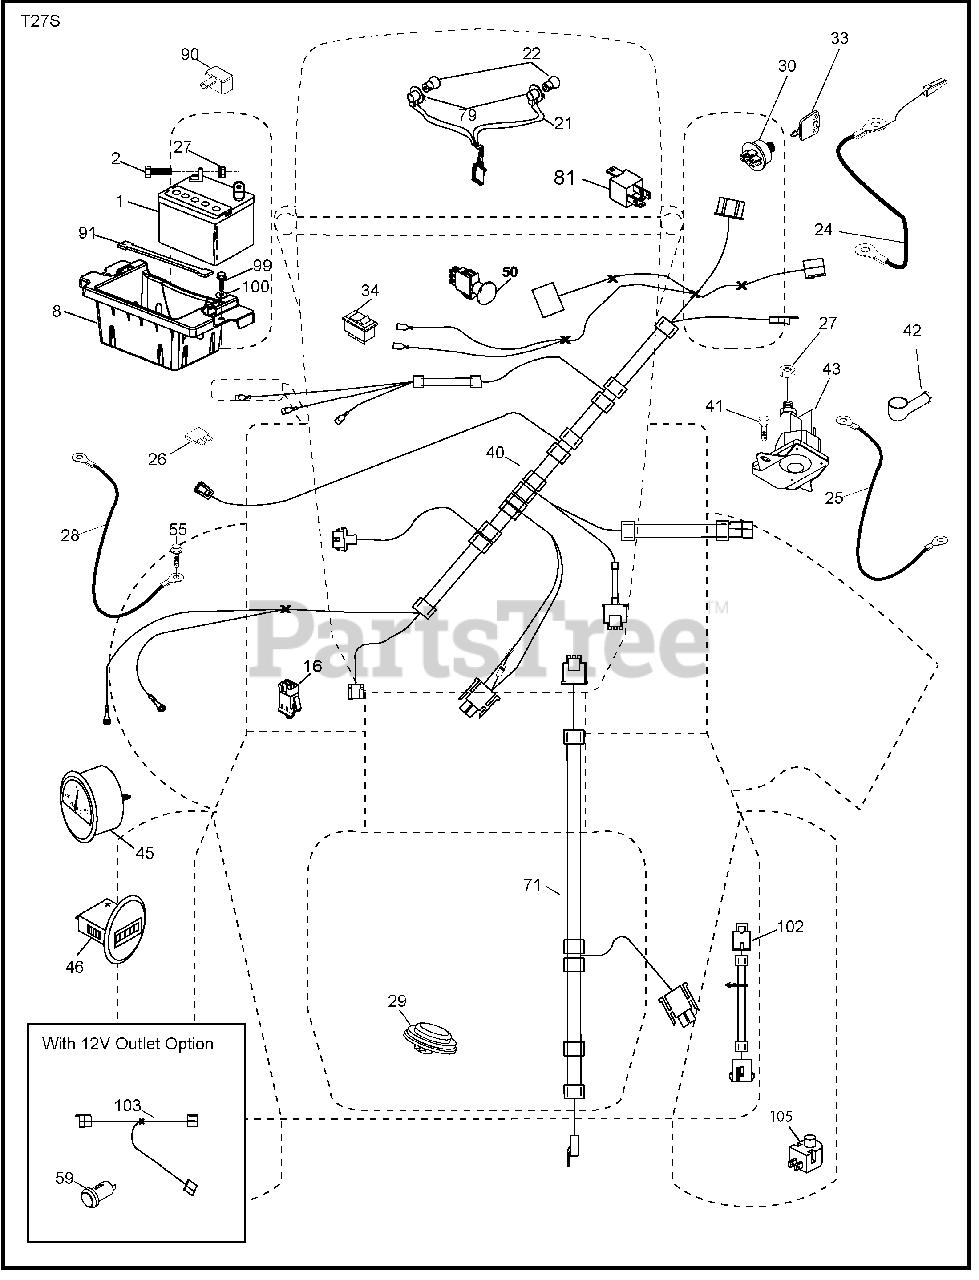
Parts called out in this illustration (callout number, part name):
1	Battery
2	Bolt Hex Head 1/4-20 X 3/4
8	Box Battery
16	Switch Interlock Push-In
21	Harness Socket Light W/4152J
22	Bulb Light
24	Cable Battery
25	Cable Starter
27	Nut Keps Hex 1/4-20 Unc
28	Cable, Ground
29	Switch, Seat
30	Switch, Ign
34	Switch Light / Reset
40	Harness Ign. Dash
41	Screw Thd Cut 1/4-20 X 1/2
42	Cover, Terminal
43	Solenoid
45	Ammeter Gauge Round
46	Gauge Servicereminder Hrmtr
50	Switch Pto
55	Screw Thdrol 5/16-18 X 3/4 Tytt
59	Outlet 12-Volt
71	Harness Ign.
79	Socket Asm Bulb Twistlock
81	Relay Harness Sealed
90	Cover Terminal
91	Strap Battery Mount
99	Screw Hexwsh Thdrol 1/4-20 X 3/4
100	Washer 9/32 X 7/8 X 16 Ga.
102	Harness Pigtail
103	Harness 12-Volt Pigtail
105	Switch Reverse Tt Pedal Control
